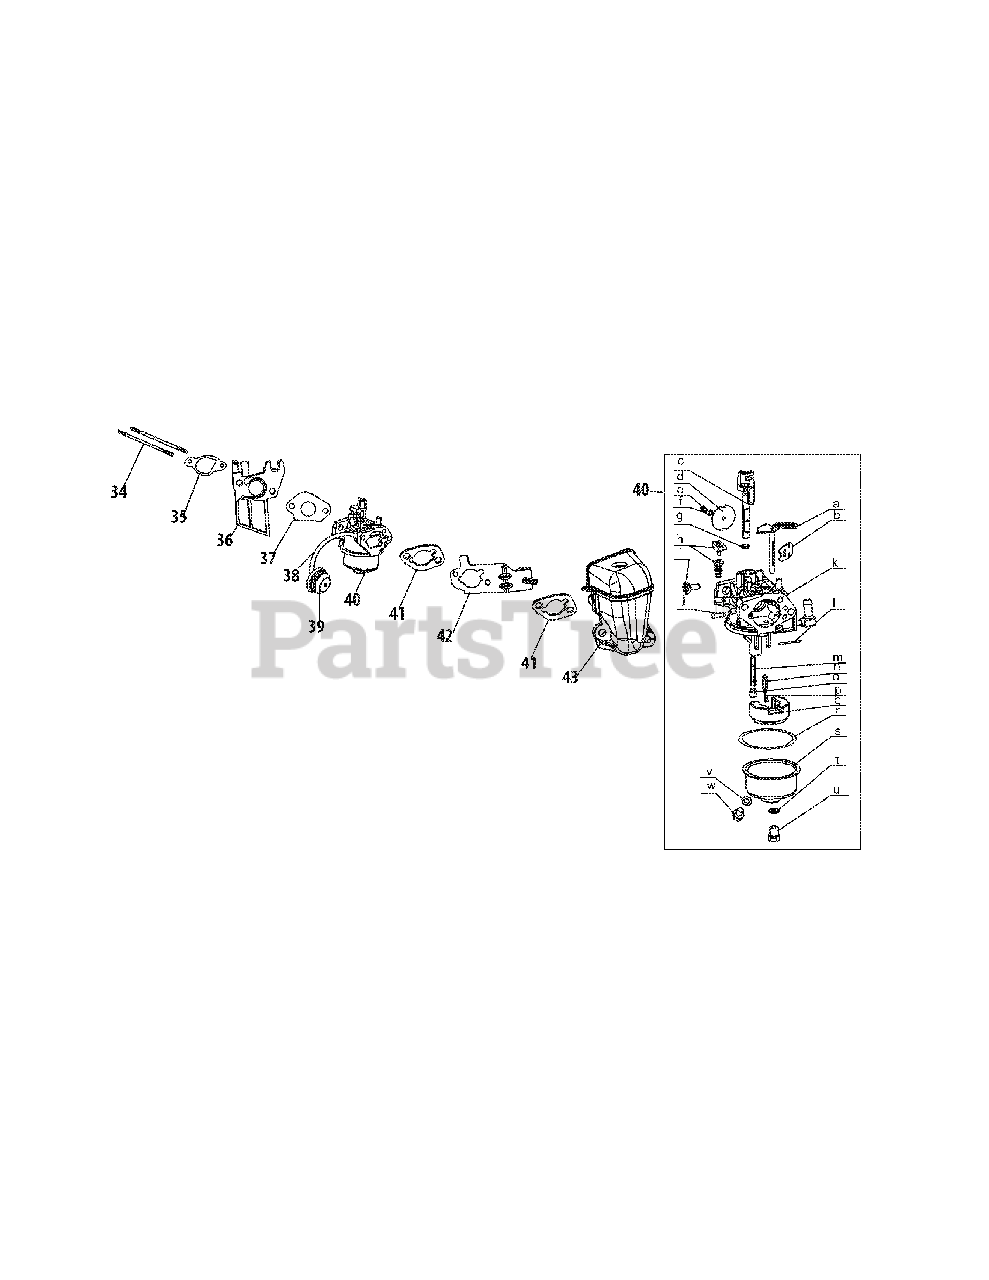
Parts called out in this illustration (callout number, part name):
34	Stud, M6×92
35	Gasket, Carburetor Insulator
36	Insulator
37	Gasket, Carburetor
38	Fuel Hose, 3.2×6.5×150
40	Carburetor
41	Gasket, Air Filter
42	Choke Controller Assembly
43	Heater Box
